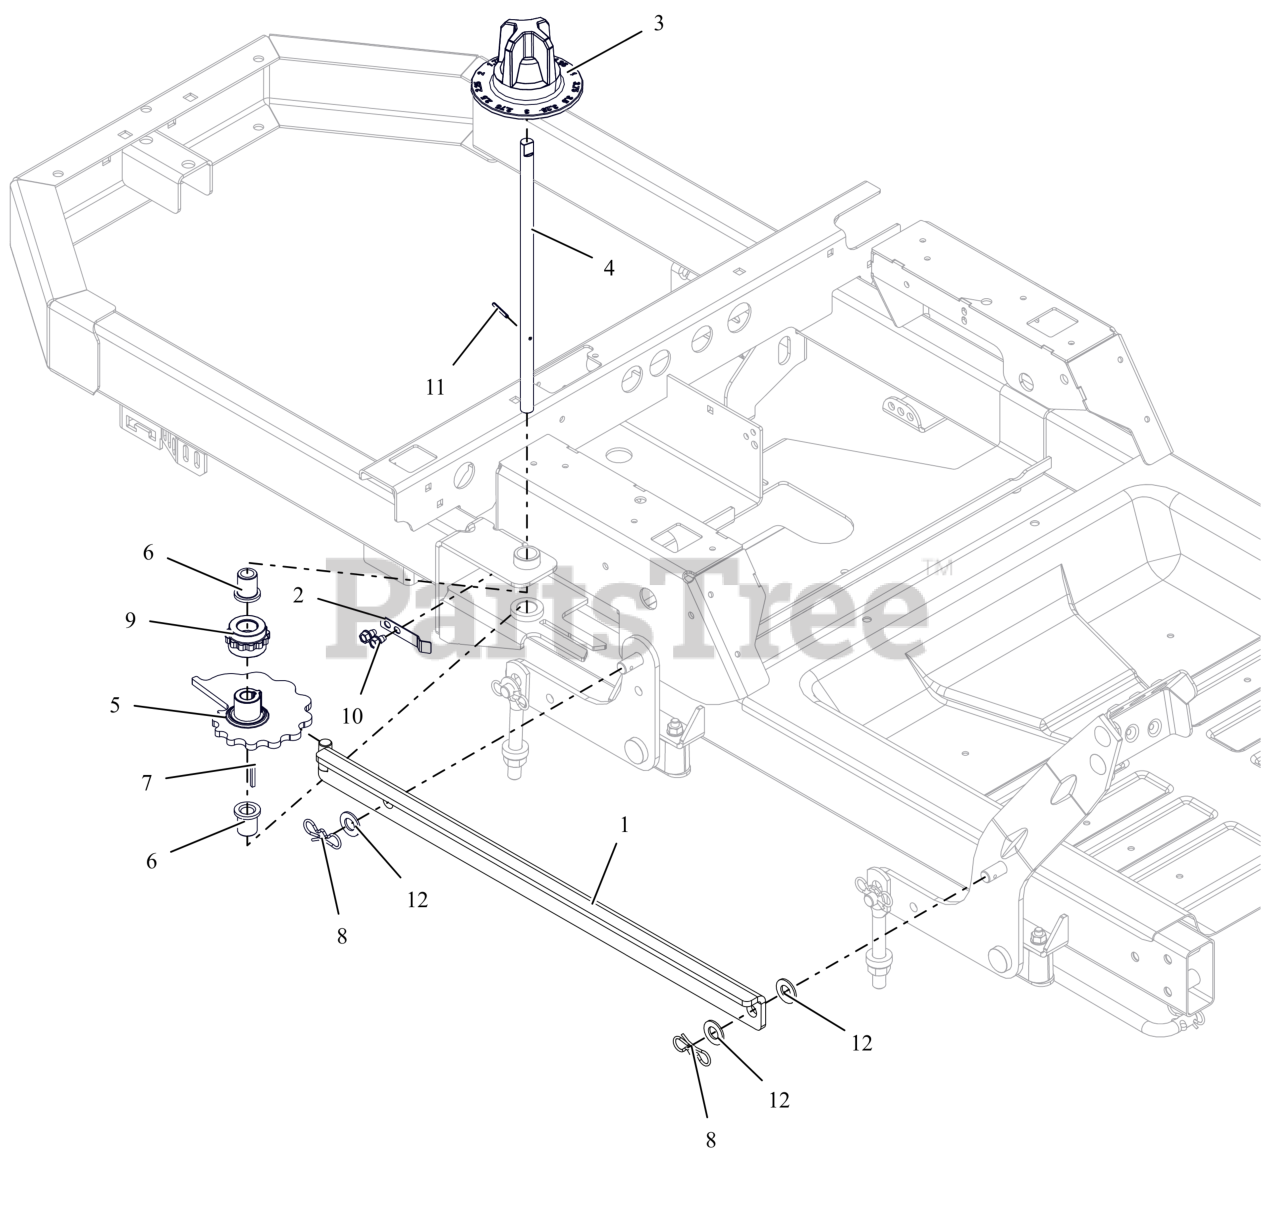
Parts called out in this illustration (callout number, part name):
1	WLDMT, HOC LINK
2	ARM, HOC DETENT
3	KNOB, HOC DIAL
4	SHAFT, HOC CAM IKON
5	CAM, HOC (PM)
6	BSHG-FLG, .503X.750X.875X1.00
7	KEY, 1/8 X 1/8 X 1.0
8	PIN, BOWTIE .091X1.875 ZCC
9	GEAR, HOC INDEX
10	SCR,TAP .25-20X.375 HWH TR ZCC
11	PIN-ROLL .125X1.00
12	WSHR-FL-NYL .518X1.000X.080
